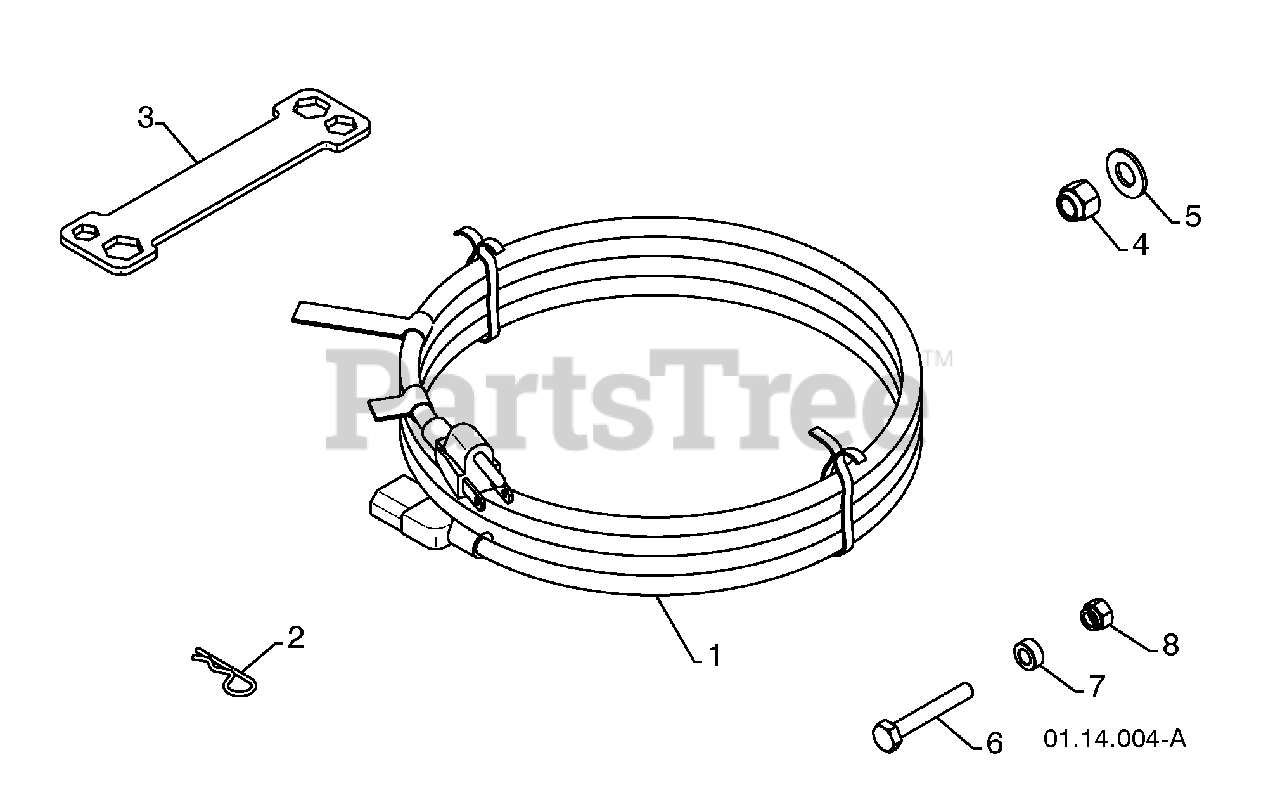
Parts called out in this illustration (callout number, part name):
1	POWER CORD
2	RETAINER PIN
3	WRENCH
4	LOCKNUT 3/8-16
5	WASHER 3/8
6	SHEAR BOLT 1/4-20 X 1-3/4
8	LOCKNUT 1/4-20
